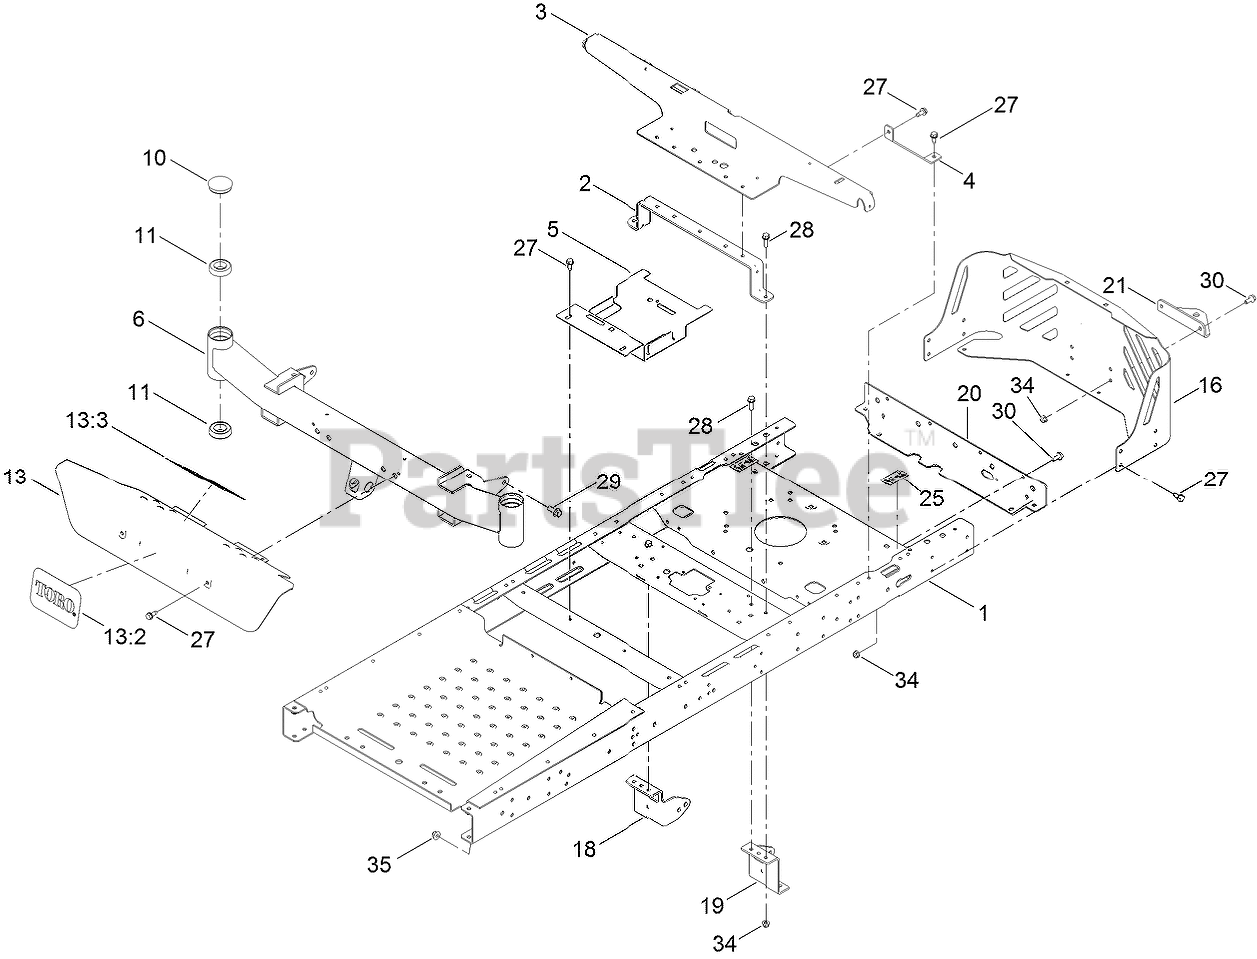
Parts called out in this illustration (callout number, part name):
1	RIVETED FRAME ASM (WIDE LEVER)
2	BRACE-SEAT, REAR (WIDE)
3	SUPPORT-POD
4	SUPPORT-TANK, REAR
5	BRACKET-BATTERY
6	AXLE-WIDE
10	CAP-GREASE
11	BEARING-BALL
13	FOOTREST ASM
13:2	DECAL
13:3	DECAL-DANGER
16	GUARD-ENGINE, WIDE
18	MOUNT-HYDRO, FRONT (RIGHT)
19	MOUNT-HYDRO, FRONT (LEFT)
20	CROSSMEMBER-REAR, WIDE
21	BRACKET-HITCH
25	DECAL-BYPASS
27	SCREW-HWHTF
28	SCREW-HHF
29	SCREW-HHF
30	SCREW-HHF
34	NUT-HF, NI
35	NUT-HF, NI
